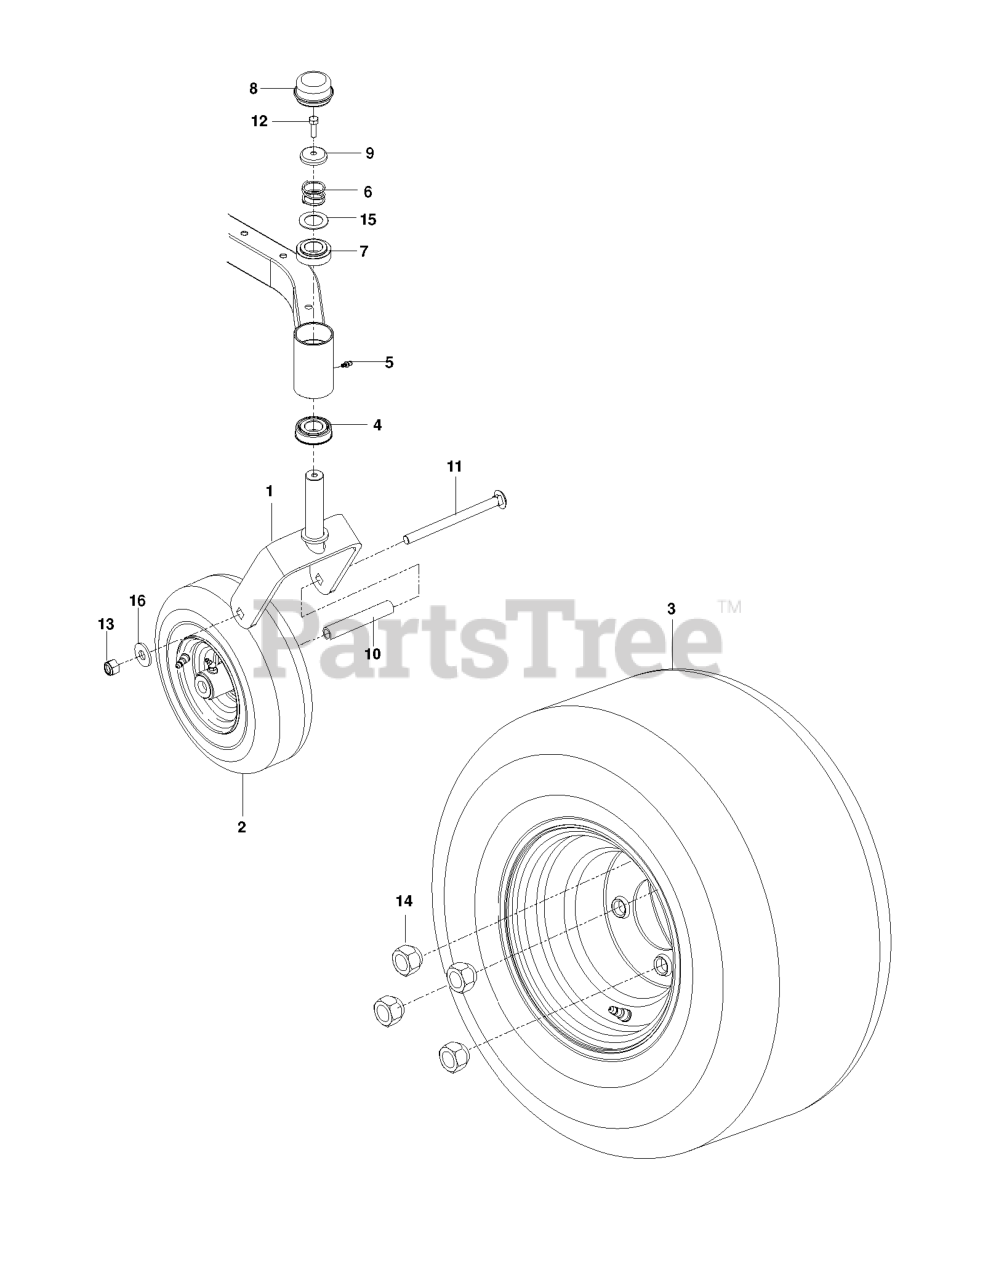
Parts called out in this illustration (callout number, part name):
1	YOKE.CASTER.ORANGE
2	WHEEL ASSY, WIDE, RZ
3	WHEEL.A500.18 X 9.5-8.SILVER
4	BEARING FLANGED
5	ZERK, 3/16, DRIVE IN
6	SPRING, CASTER
7	BUSHING, CASTER
8	GREASE CAP
9	CASTER.PLUG
10	SPACER, PIVOT
11	RHSNB 1/2-13 X 7.5
12	5/16-18X1 HHB G5W/NY
13	NUT 1/2-13 HEX CNTRLK GR 5 ZD
14	LUG NUT 1/2F
15	WASHER, 1.025 ID X 1.64
16	WASH USS FLAT 1/2
